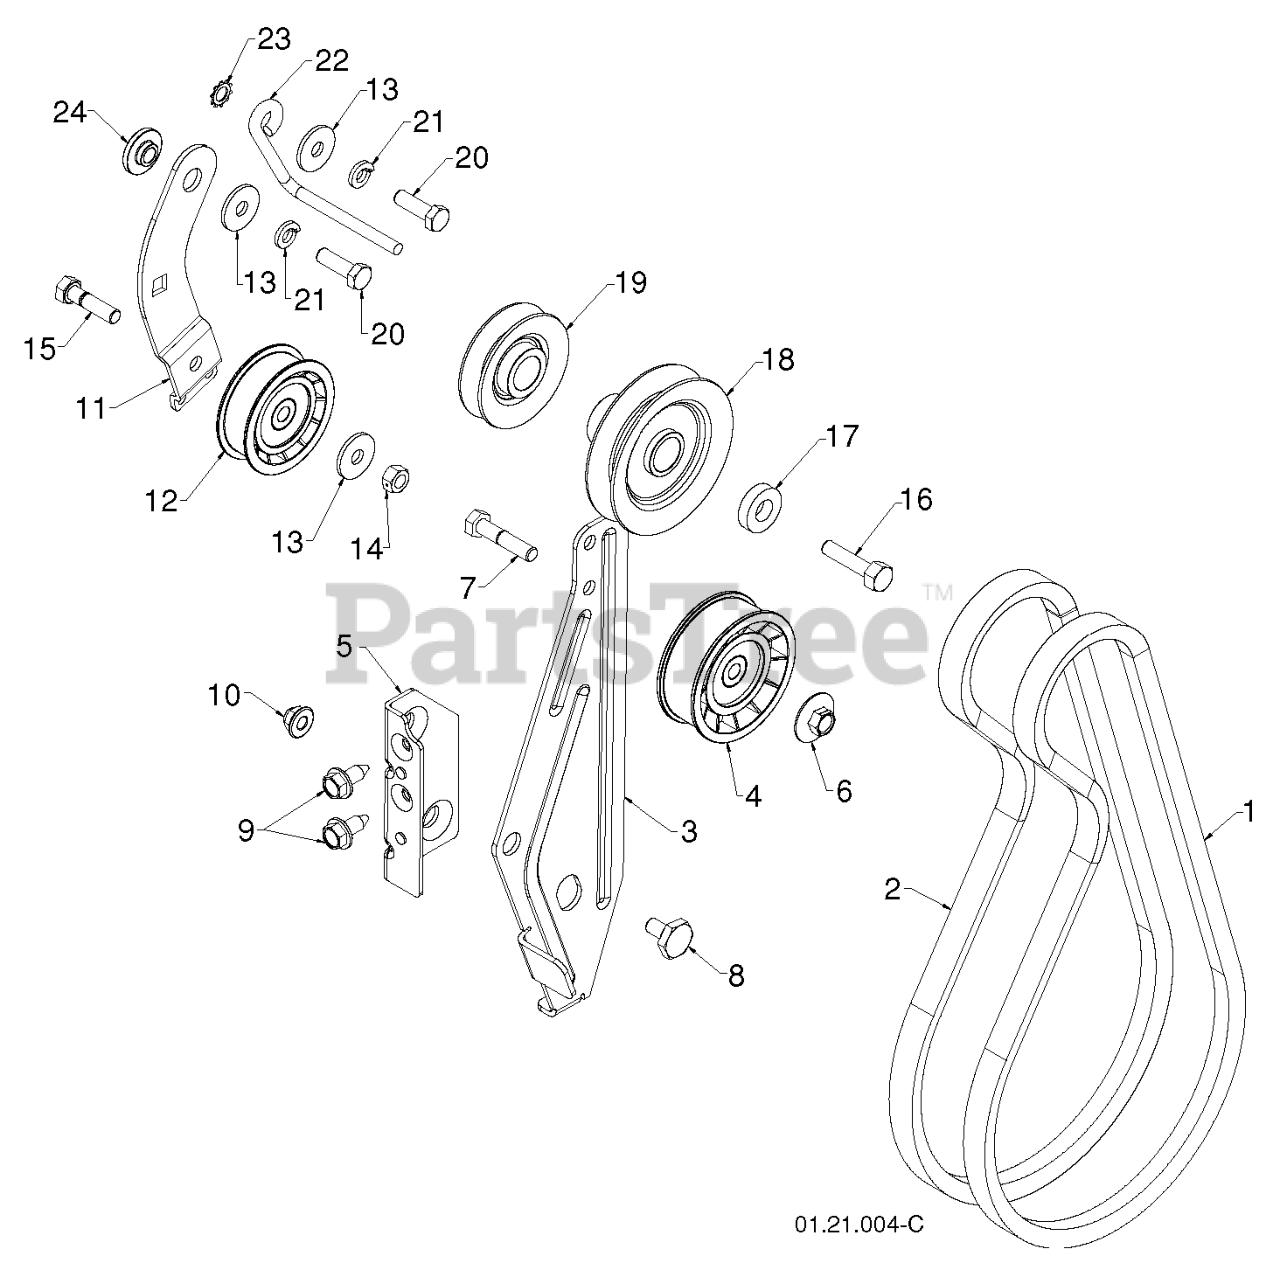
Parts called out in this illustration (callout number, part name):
1	VBELT; IMPELLER_39.09
2	V-BELT TRACTION 34.25
3	ARM.IDLER.BRAKE.
4	PULLEY.IDLER.W/SPACER.
5	RP BRACKET.IDLER.PIVOT
6	NUT.FLANGE.HEX.5/16X18.BLACK
7	HEX BOLT
8	BOLT.SHOULDER.1/2X12
9	BOLT.HEX.HD.WASHER.5/16-18X.75
10	NUT.LOCK.5/16-18
11	ARM, IDLER
12	PULLEY.W/SPACER.2.25
13	STEEL WASHER
14	NUT.71038.31-18.HEX.NYLOCK
15	BOLT.5/16-18X1-1/4 FULL.THREAD
16	SCREW, HEX HD 3/8-24 X 1-3/8
17	WASHER, FLAT 3/8
18	PULLEY.ENG.IMPELLER.SNOW
19	PULLEY.ENG.TRACTION
21	WASHER.LOCK.HVY.HLCL.SPR.5/16
22	BELT.GUIDE.RH
23	WASHER EXT TOOTH LOCK 5/16
24	RP BUSHING, IDLER PIVOT
